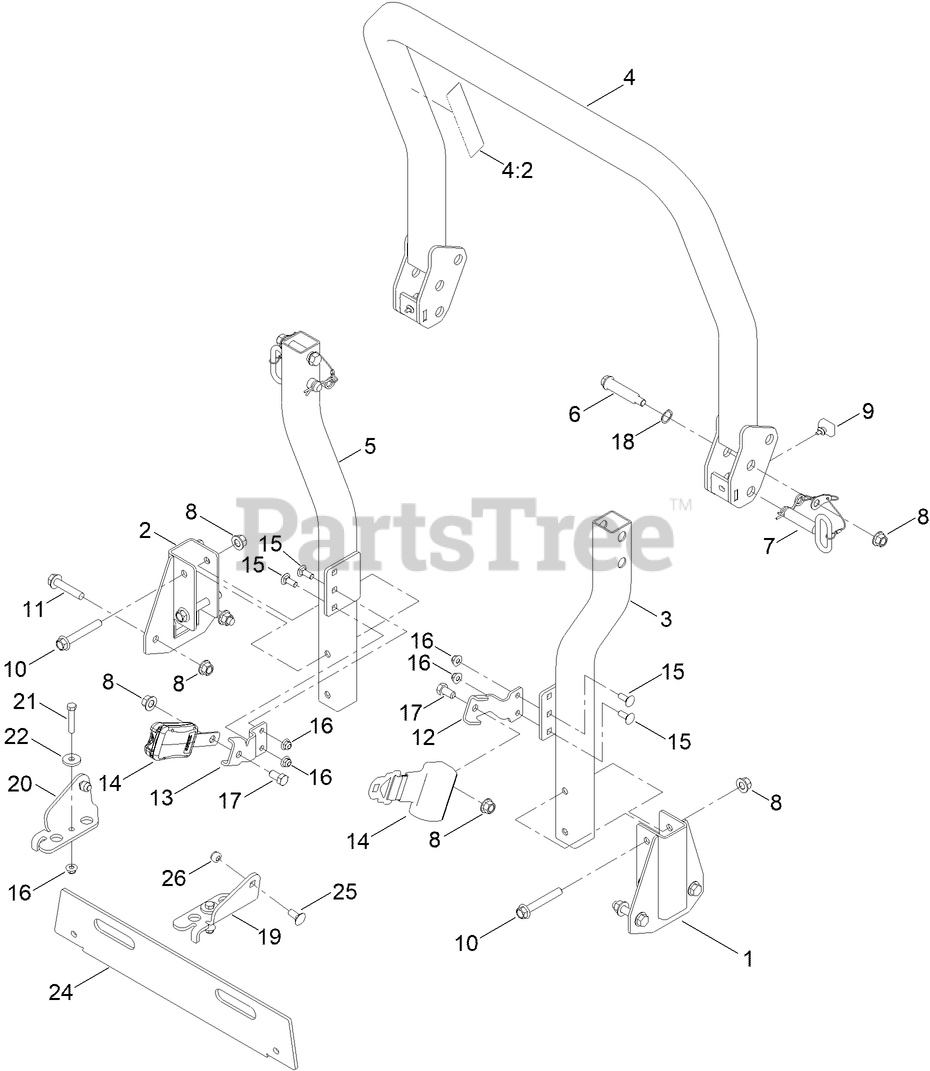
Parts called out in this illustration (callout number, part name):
1	BRACKET ROPS LH [BLACK]
2	BRACKET ROPS RH [BLACK]
3	TUBE-ROPS, LOWER LH [BLACK]
4	TUBE-ROPS, UPPER ASM
4:2	DECAL-WARNING
5	TUBE-ROPS, LOWER RH [BLACK]
6	BOLT-SHOULDER
7	PIN-ROPS, ASM
8	NUT-HF
9	BUMPER-ROPS
10	SCREW-HHF
11	SCREW-HHF
12	BRACKET-SEAT BELT, LH
13	BRACKET-SEATBELT, RH
14	SEAT BELT KIT
16	NUT-HF, NI
17	SCREW-HH
18	WASHER-WAVE
19	BRACKET - LH SEAT BELT
20	BRACKET - RH SEAT BELT
21	HHCS 3/8-16 X 2, GR5, CZ
22	WASHER-HARDENED, CZ
24	WEIGHT-BAGGER
25	SCREW-CARR
26	NUT-HEX, NI
